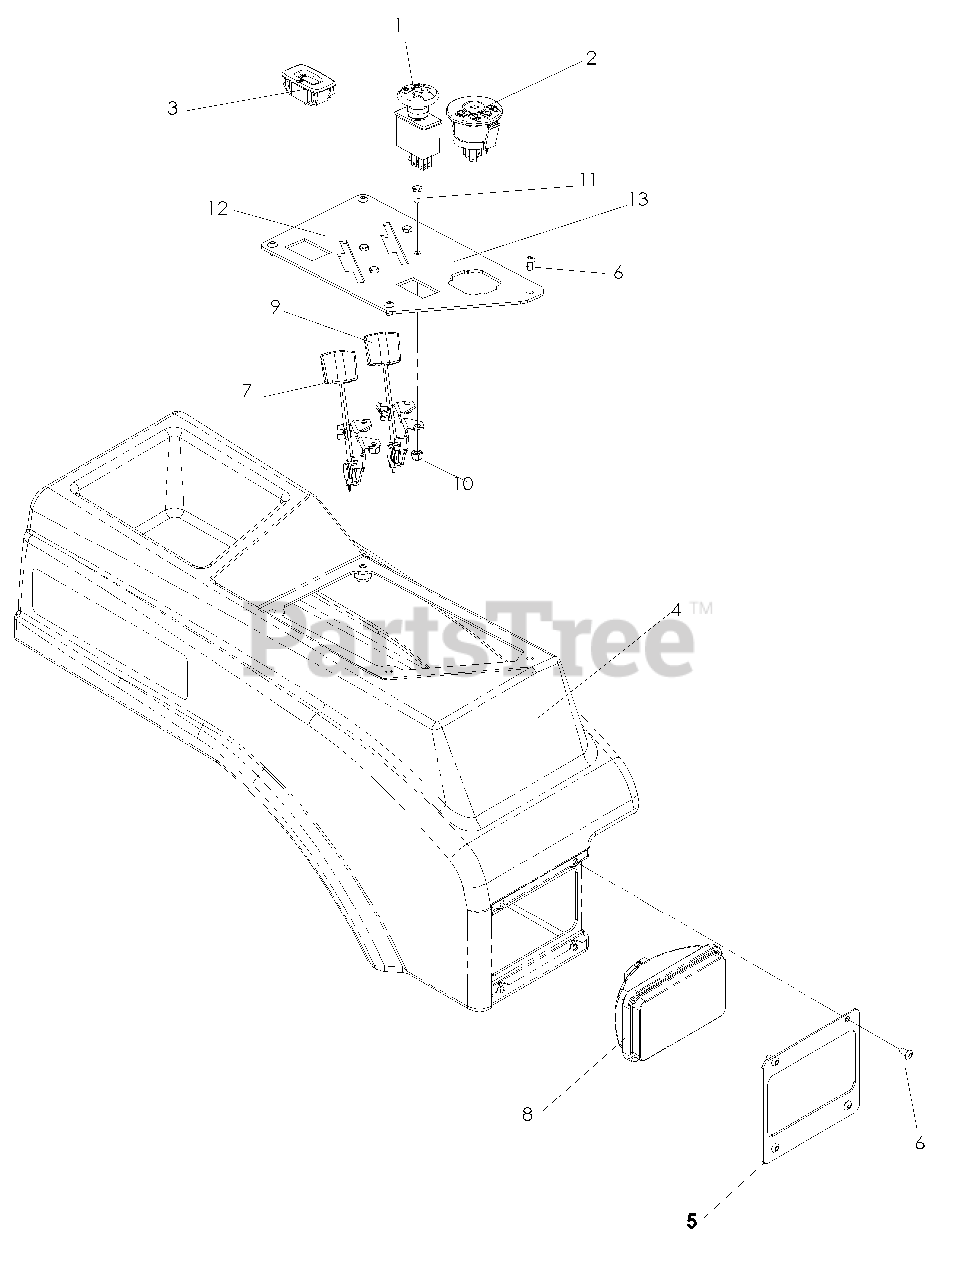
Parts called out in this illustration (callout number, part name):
1	SWITCH, BLADE
2	IGNITION SWITCH
3	HOUR METER
4	TANK, CONSOLE, RT
5	PLATE LIGHT
6	SCR #10-24 X 3/8 SKT HD BLK OX
7	CABLE THROTTLE
9	CABLE CHOKE
10	NUT 10-24 NYLOC
11	HCS #10-24 X 1/2
12	CONTROL PANEL
13	DECAL, CONTROL
